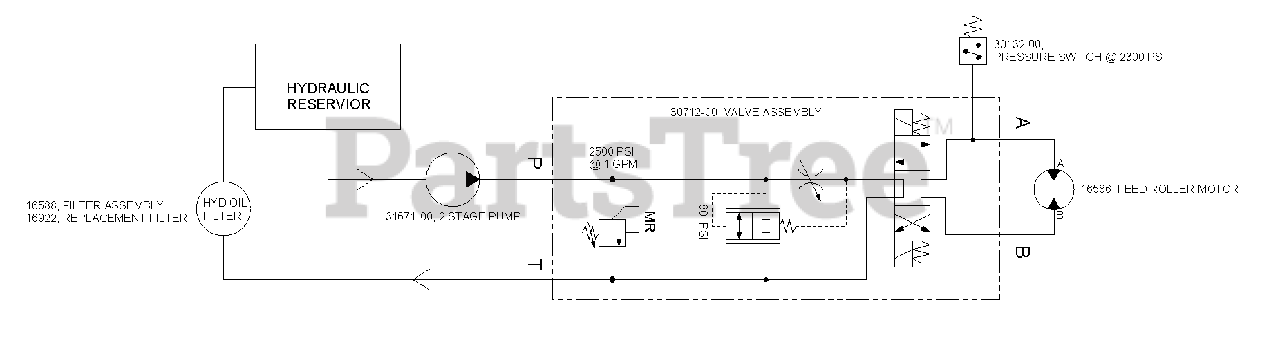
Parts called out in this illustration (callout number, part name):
1	BUMPER, RUBBER
2	GRIP, 1.219 X 10.00
3	LATCH, RH HINGE
4	BOLT, 3/8 X 1" GR5 CRG NC ZP
5	BOLT, 3/8 X 1-1/2" GR5 CRG NC ZP
6	BOLT, 3/8 X 1-1/4 FLANGE NC
7	BOLT, 5/16 X 3/4 FLANGE NC
8	BOLT, 3/8 X 1 FLANGE NC
9	WASHER, 5/16" FLAT ZP
10	WASHER, 3/8" SAE FLAT ZP
11	WASHER, 3/4 INTERNAL LOCK
12	BOLT, 5/16 X 1" GR5 CRG ZP
13	BOLT, 5/16 X 3/4 GR5 CRG NC ZP
14	NUT, 3/8" NE NYLOCK ZP
15	BOLT, 5/16 X 1-1/4" GR5 CRG ZP
16	WASHER, 5/16" ID 7/8" OD NYLON FLAT
17	RIVET, AL BLIND 1/4 X 3/4 DOME HEAD
18	NUT, 5/16-18 NYLOCK-FLANGE
19	NUT, 3/8-16 NYLOCK FLANGE
20	SPRING, 1/2 X 2.00 LG ZP
21	CLAMP, CABLE MOUNT
22	DECAL, BEARCAT WEB
23	SENSOR, M18 PROXIMITY (REPLACEMENT PART)
24	SPACER, IDLER PIVOT
25	HINGE, EXTENSION TRAY
26	MOUNT, 5/8/9" DDC
27	MOUNT, 5/8/9" KNEEBAR PROX SENSOR
28	WELDMENT, INFEED TRAY
29	WELDMENT, 9" TOWABLE KNEE BAR
30	ASSEMBLY, DDC ENCLOSURE
31	WELDMENT, CHUTE SUPPORT
32	LINK, PARALLEL
33	WELDMENT, KNEEBAR PIVOT
